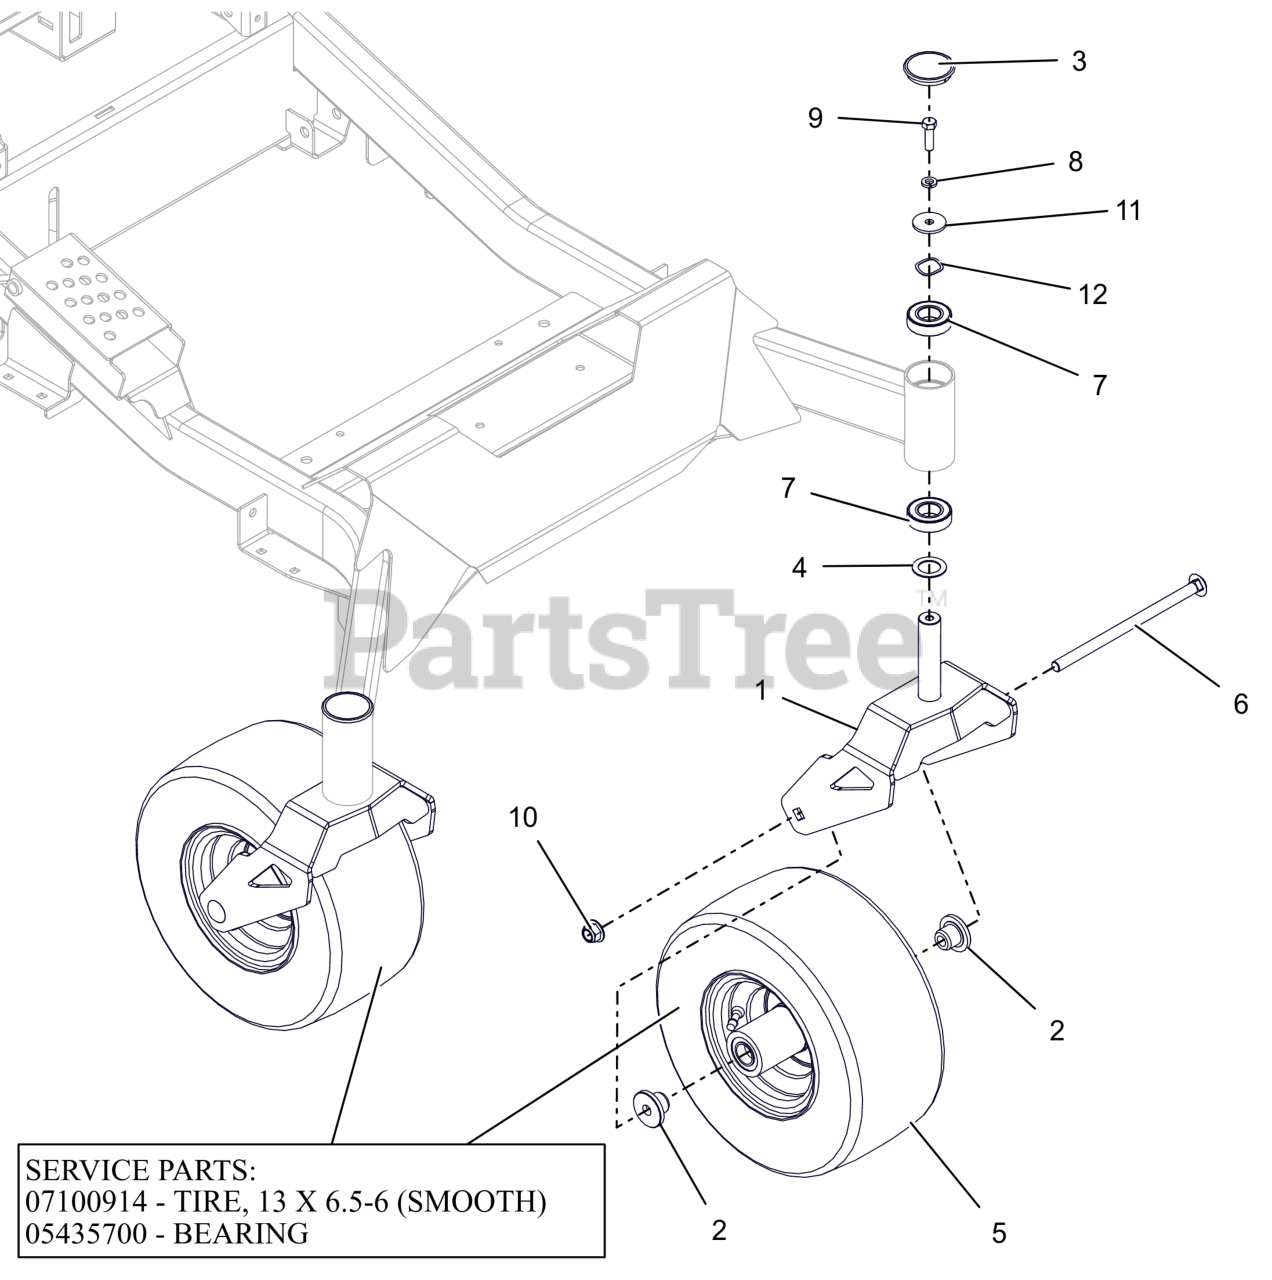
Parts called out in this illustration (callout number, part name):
1	WLDMT, HD CASTER FORK
2	SPACER, FRONT WHEEL
3	CAP, DUST
4	WSHR-HRD-THRS 1.007X1.542X.062
5	ASM, WHL/TIRE 13X6.50-6
5	TIRE, 13X6.50-6 SMOOTH
5	BRG, 25MM ID X 52MM OD X 15MM
6	BLT, RHSN .50-13X9.00 G5 ZCC
7	BRG,BALL 1.00X2.00X.563(1641)
8	WSHR, LK-HVY .375X.115 ZCC
9	BLT, HEX .38-16X1.25 G5 ZCC
10	NUT,NYL-FLG .50-13 GF ZCC
11	WSHR, FLT .380X1.50X.125 ZCC
12	WSHR-WAVE 1.0X1.25X.028 .145FH
